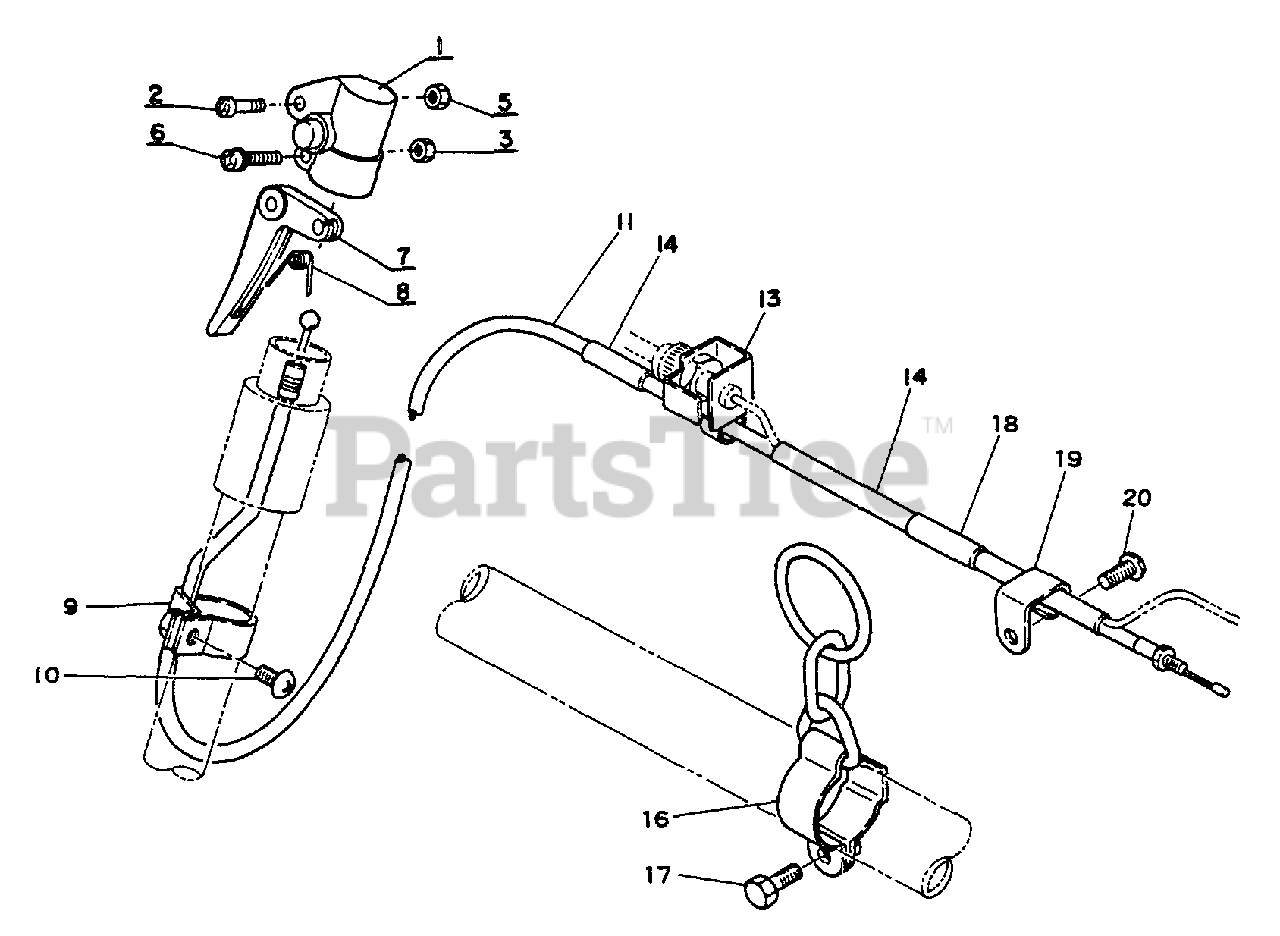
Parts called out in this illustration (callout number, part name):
1	CLAMP, THROTTLE CONTROL
3	NUT M5
5	LOCKNUT - 5
6	SCREW 5×28
7	TRIGGER, THROTTLE
10	SCREW 5×10
11	CABLE, THROTTLE
14	TUBE
16	HANGER KIT
17	BOLT 5×12
18	TUBE
19	CLAMP
20	SCREW 5×8
